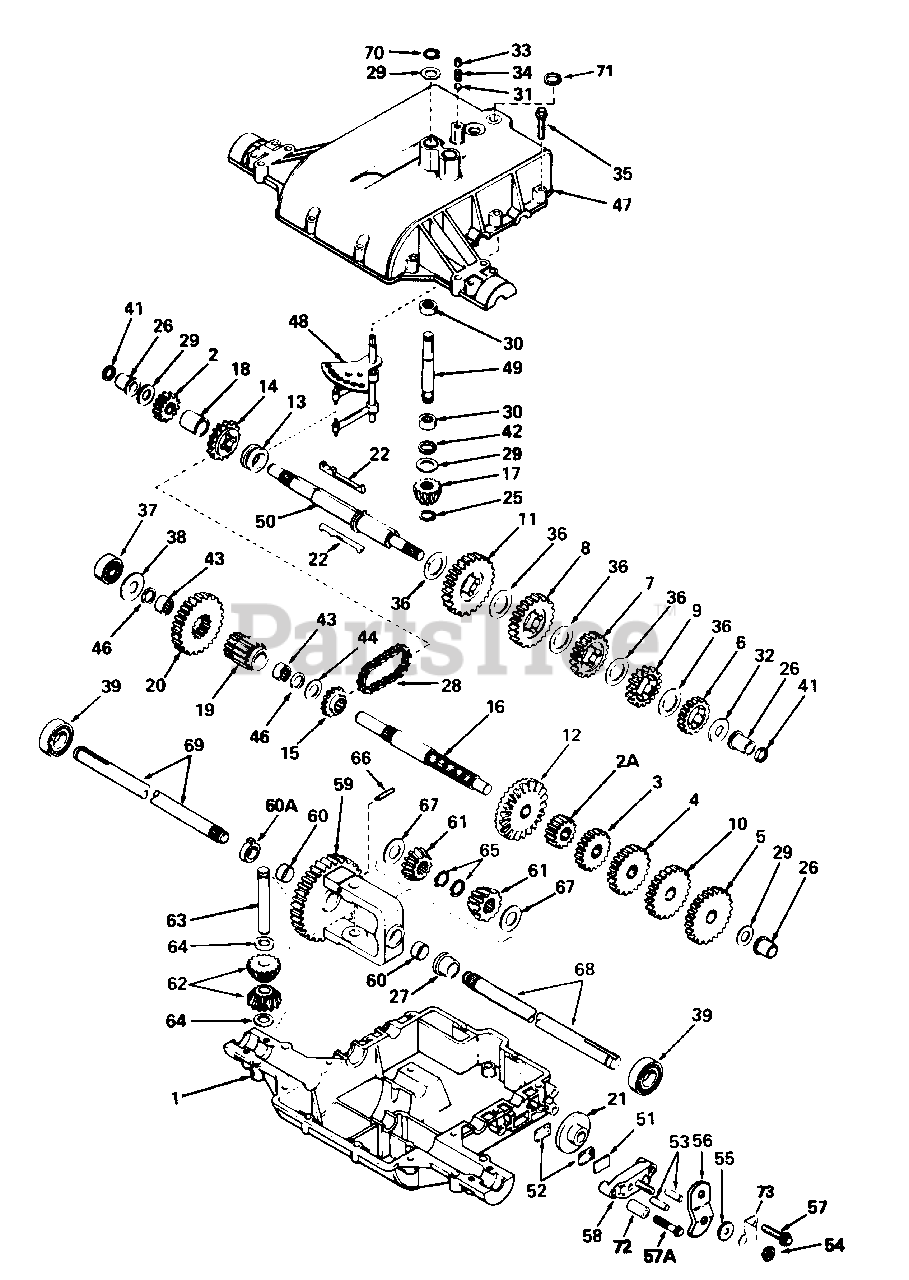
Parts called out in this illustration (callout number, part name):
1	CASE, Transaxle
2	GEAR, Spur (15 teeth)
2A	GEAR, Spur (12 teeth)
3	GEAR, Spur (20 teeth)
4	GEAR, Spur (25 teeth)
5	GEAR, Spur (30 teeth)
6	GEAR, Spur (20 teeth)
7	GEAR, Spur (25 teeth)
8	GEAR, Spur (30 teeth)
9	GEAR, Spur (22 teeth)
10	GEAR, Spur (28 teeth)
11	GEAR, Spur (37 teeth)
12	GEAR, Spur (42 teeth)
13	COLLAR, Shift
14	SPROCKET (14 teeth)
15	SPROCKET (10 teeth)
16	SHAFT, Counter
17	BEVEL PINION, Input
19	PINION, Output
20	GEAR, Output
21	DISK, Brake
25	RING, Retaining
26	BUSHING, Flanged
27	BUSHING, Flanged
28	CHAIN, Roller (No. 41 chain, 22 links)
29	WASHER, Thrust
30	BEARING, Needle
31	BALL, Steel
32	WASHER, Thrust
33	SCREW, Set, 3/8-16 x 3/8
35	SCREW, Hex Hd., Thread Forming, 1/4-20 x 1-1/4
36	WASHER, Thrust
37	BEARING, Ball
38	WASHER, Flat
39	BEARING, Ball
41	SEAL, Square Cut
42	SEAL, Square Cut
43	BEARING, Needle
44	WASHER, Flat
46	SEAT, Square Cut
47	COVER, Transaxle
48	ROD & FORK ASSY., Shift
49	SHAFT, Input
50	SHAFT, Brake
51	PLATE, Brake Pad
52	PAD, Brake
53	PIN, Dowel
54	LOCKNUT, 5/16-24
55	WASHER, Flat
56	LEVER, Brake
57	SCREW, Hex Hd. Thd. Form., 1/4-20 x 1-1/4
57A	SCREW, Hex Hd., Thd. Form., 1/4-20 x 2-1/4
58	HOLDER, Brake Pad
59	GEAR ASSY., Differential (Incl. 2 of No. 60)
61	GEAR, Bevel
62	PINION, Bevel
63	PIN, Drive
64	WASHER, Thrust
65	RING, Retaining
66	PIN, Roll
67	WASHER, Thrust
68	AXLE (15-1/2" long)
69	AXLE (12-1/2" long)
70	RING, Retaining
71	SEAL, Square Cut
